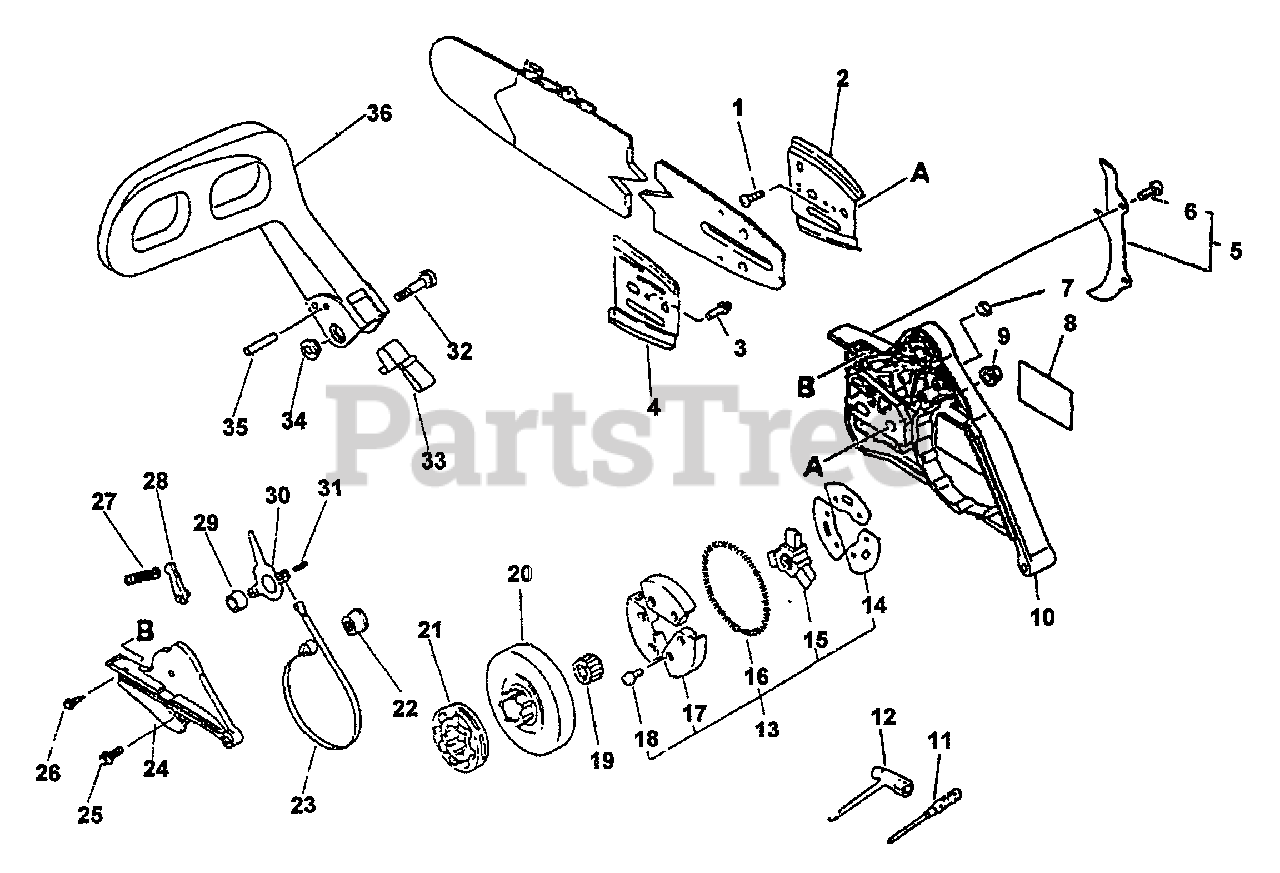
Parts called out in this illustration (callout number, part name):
1	SCREW - 3X6
2	PLATE, GUIDE - OUTER
3	SCREW - 4X8
4	PLATE, GUIDE - INNER
5	SPIKE KIT
8	LABEL - ECHO
9	NUT - FLANGE
10	GUARD, SPROCKET
11	SCREWDRIVER
12	T-WRENCH - 13X19mm
13	CLUTCH ASSY
14	PLATE, CLUTCH
15	HUB, CLUTCH
16	SPRING, CLUTCH
17	CLUTCH SHOE SET
18	SCREW - 4X6
19	BEARING, NEEDLE
20	DRUM, CLUTCH
21	SPROCKET, RIM
22	ADJUSTER, BRAKE BAND
23	BAND, BRAKE
24	COVER, BRAKE
25	SCREW - 3X18
26	SCREW - 4X12
27	SPRING, BRAKE
28	STOPPER, BRAKE
29	SPACER - 8
30	LEVER, BRAKE
31	PIN - SPRING -- 4X8
32	MOUNTING KIT
33	SPRING, RETURN
35	PIN - 3.5X26
36	LEVER, BRAKE
